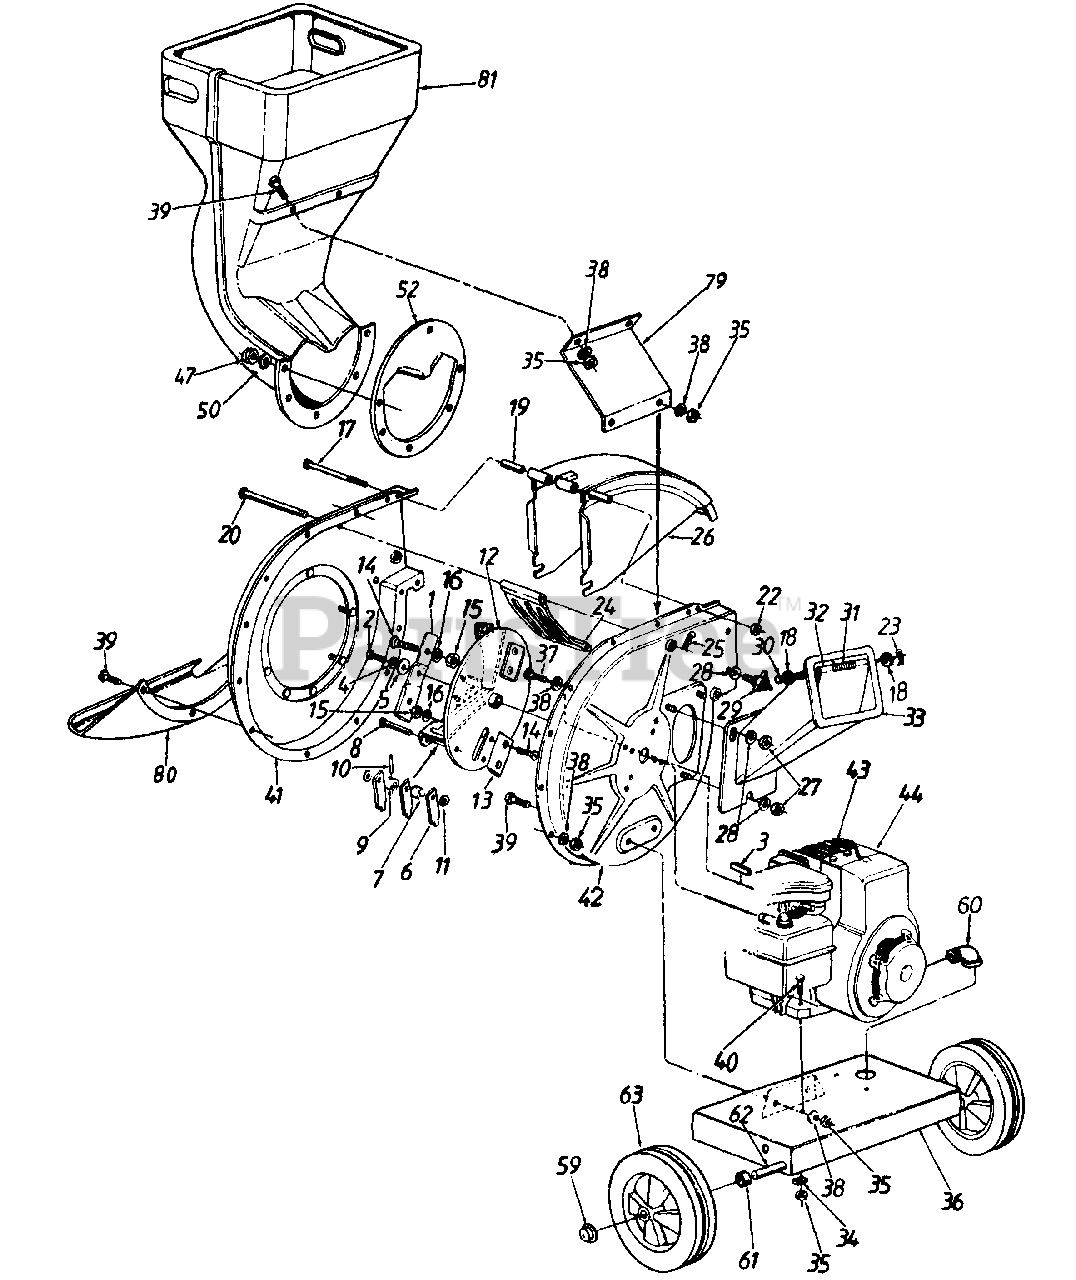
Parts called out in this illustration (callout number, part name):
2	Hex Patch Bolt 3/8-24 x 2" Lg. (Gr. 8)
2	Hex Patch Bolt 3/8-24 x 2.25" (Gr. 8)
3	Sq. Key 1/4 x 2.0" Lg.
4	L-Wash. 3/8" I.D. H.D.
5	Fl-Wash. .406" I.D. x 1.25" O.D. Hdn.
6	Flail
7	Flail Spacer
8	Clevis Pin .496" Dia.
9	Flail Spacer w/.160" Dia. Hole
10	Spring Roll Pin 1.12" Lg.
11	Fl-Wash. .531" I.D. x .94" O.D.
12	Impeller Ass'y. Comp.
13	Chipper Blade
14	Flat Hd. Scr. 5/16-24 x .75" Lg.
15	Hex Top L-Nut 5/16-24 (Gr. 5)
16	L-Wash. 5/16" I.D.
17	Hex Bolt 1/4-20 x 3.75" Lg.
18	Fl-Wash. .281" I.D. x .5" O.D.
19	Chute Hinge Spacer 1.66" Lg.
20	Clevis Pin .5" Dia. x 4.62" Lg.
22	Hex Ctr. L-Nut 1/4-20 Thd.
23	Cotter Pin 3/32" x 5/8"
24	Shredder Screen
25	Internal Cotter Pin 3/8" Dia.
27	Hex Nut 5/16-18 Thd. (Gr. 5)
28	Bell-Wash. .345" I.D. x .88"
29	Hand Knob
30	Chipper Door Rod
31	Torsion Spring 1.14" Lg.
35	Hex Nut 5/16-18 Thd. (Gr. 5)
37	Hex Bolt 5/16-24 x .75" Lg.
38	L-Wash. 5/16" I.D.
39	Hex Bolt 5/16-18 x .75" Lg. (Gr. 5)
40	Hex Bolt 5/16-18 x 1.75" Lg.
44	Engine
47	Elastic Lock Nut 5/16-18 Thd.
50	Fl-Wash. 5/16" I.D.
52	Back-Up Plate
59	Push Cap 5/8" Dia. Rod
60	Drain Elbow
61	Spacer .64" I.D. x .38" Lg.
62	Shredder Axle
63	Wheel Ass'y. Comp.
81	Leaf Hopper
